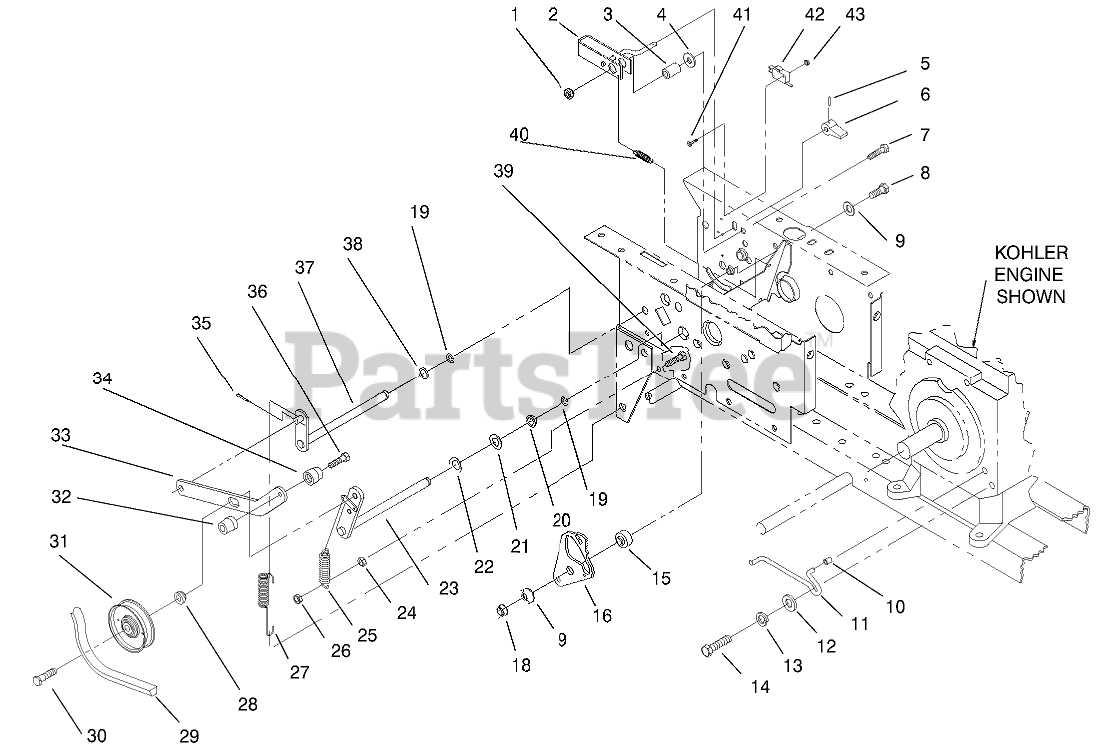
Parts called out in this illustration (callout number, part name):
1	NUT-HF
2	WLMT-BRAK (BLACK)
3	SPACER
4	WASHER-SPACER
5	PIN-SPIROL 3/32X5/8
6	KNOB-PARKING BRAKE
7	SCREW-HH
8	SCREW-HH
9	WASHER-FLAT
11	GUIDE BELT
12	WASHER-FLAT
13	WASHER-LOCK
14	SCREW-HH
15	Spacer
16	PLATE-CAM (BLACK)
18	NUT-LOCK, NI
19	RING-RETAINING, EXTERNAL
20	BUSHING-FLANGED
21	SHIM-WASHER
22	CURVED-SPRING WASHER
23	ASSY-ARM/ROD WA
24	NUT-HEX
25	SPRING-EXTENSION
26	NUT-LOCK, NI
27	SPRING-EXTENSION
28	SPACER-BRAKE LINK
29	V-BELT TRANS DRIVE
30	BOLT-SPECIAL HEX
31	PULLEY-IDLER
32	KNOB
33	HNDL BRAKE & CLUTCH (BLACK)
34	KNOB
35	PIN-COTTER
36	Screw
37	ASSY-BRAKE LEVER
38	WASHER
39	SCREW-HH
40	EXTENSION-SPRING
41	SCREW-PPH
42	SWITCH
43	NUT-HEX
